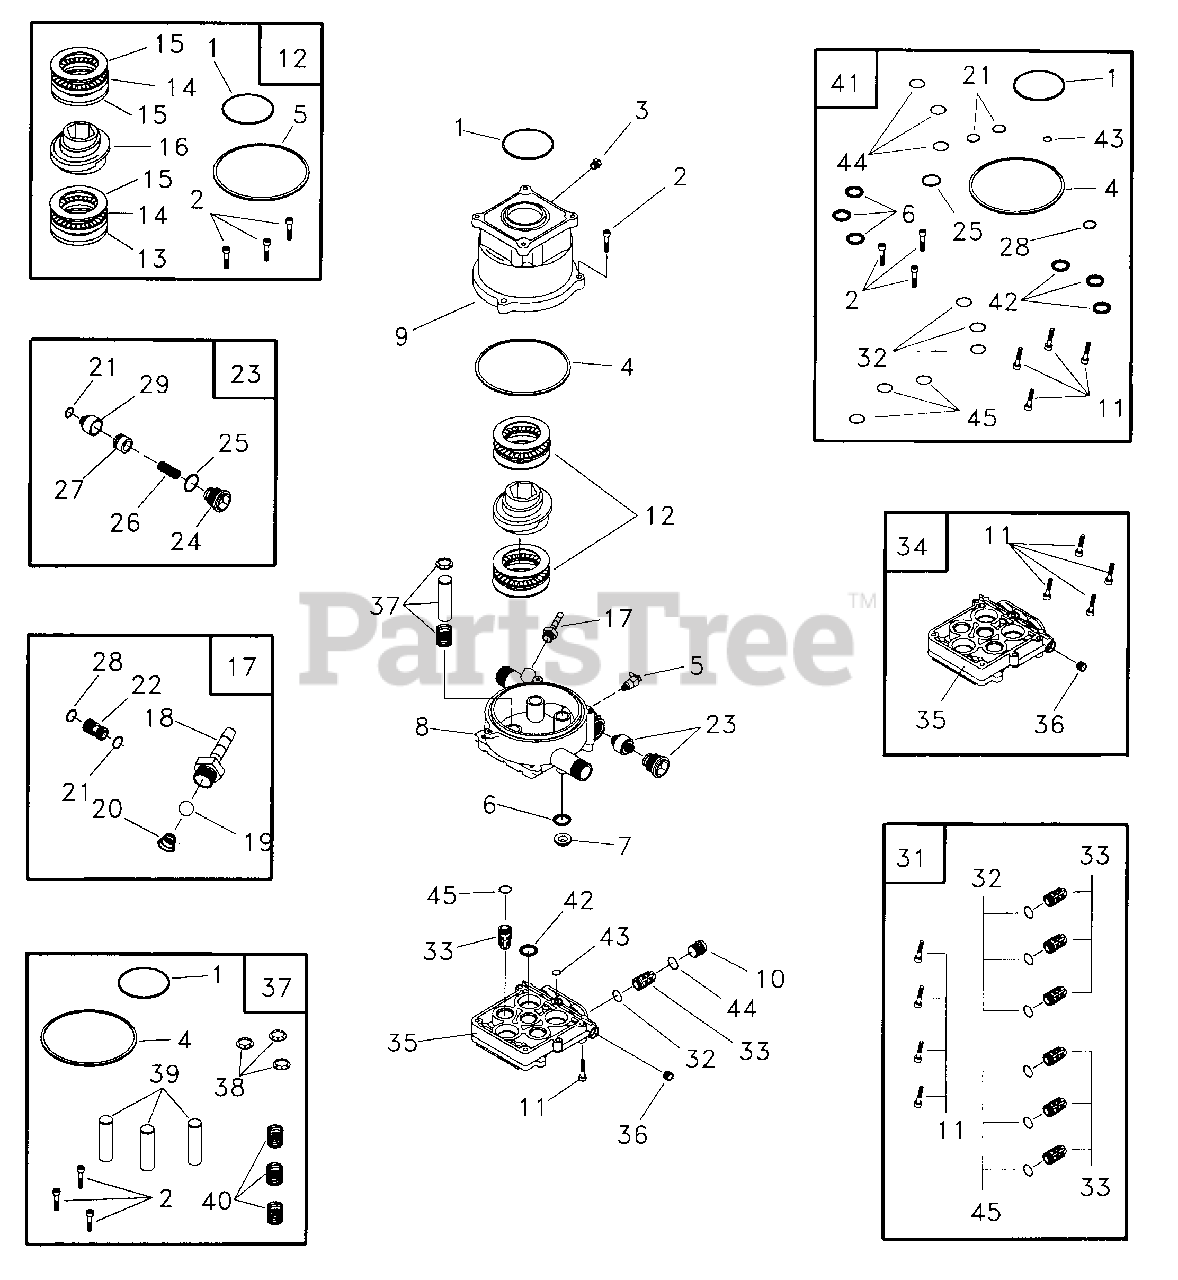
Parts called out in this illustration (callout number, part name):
1	O-RING, 1.625 ID x .103
1	O-RING, Engine Seal
2	SHCS, M6 - 1 x 25
2	SHCS, M6-1x25
2	SHCS, M6-1 x 25
2	SHCS, M6-1 x25
3	VALVE, 1/8 npt 1-5 PSI
4	O-RING, Housing Seal
4	Q-RING, Housing Seal
4	O-RING, Mousing Seal
5	VALVE, Thermal Relief
6	SEAL, Oil Piston
7	SPACER, Pilot
8	HOUSING, Piston
9	ADAPTER, Engine
10	CAP, Outlet Check Valve
11	SHCS, M6-1.0 x 35
11	SMCS, M6-1.0 x 35
12	KIT, AXIAL CAM
13	WASHER, Brg. 36 x 65 x 6Thk
14	ASSY., Brg. Cage 45 x 65
15	WASHER, Brg. 45 x 65 x 1
16	CAM, Axial 5.6 3/4"SAE
17	KIT, CHEM INJECT
18	FITTING, Chem Inject
19	BALL, Chem Inject
20	SPRING, Chem Inject
21	O-RING, Venturi 8 Seat, Black
22	VENTURI, Chem Inject
23	KIT, UNLOADER 2300
24	CAP, Unloader
25	O-RING, Unloader Cap
26	SPRING, Unloader
27	PISTON, Unloader
28	Q-RING, Venturi, Yellow
28	O-RING, Venturi, Yellow
29	SEAT, Unloader
31	KIT, CHECK VALVES
32	O-RING, Check Valve
33	ASSY., Check Valve
34	KIT, HEAD BRASS EG
35	HEAD, Pump
36	PLUG, 1/8-28
37	KIT, PISTON & SPRING
38	RETAINER, Piston Spring
39	PISTON, Dia. 15 x 65
40	SPRING, Piston Return
41	KIT, 0-RING/SEAL 2300
42	SEAL, Double-Lip
43	O-RING, High Pressure Transfer
44	O-RING, Outlet CV Cap
45	O-RING, Check Valve, White
